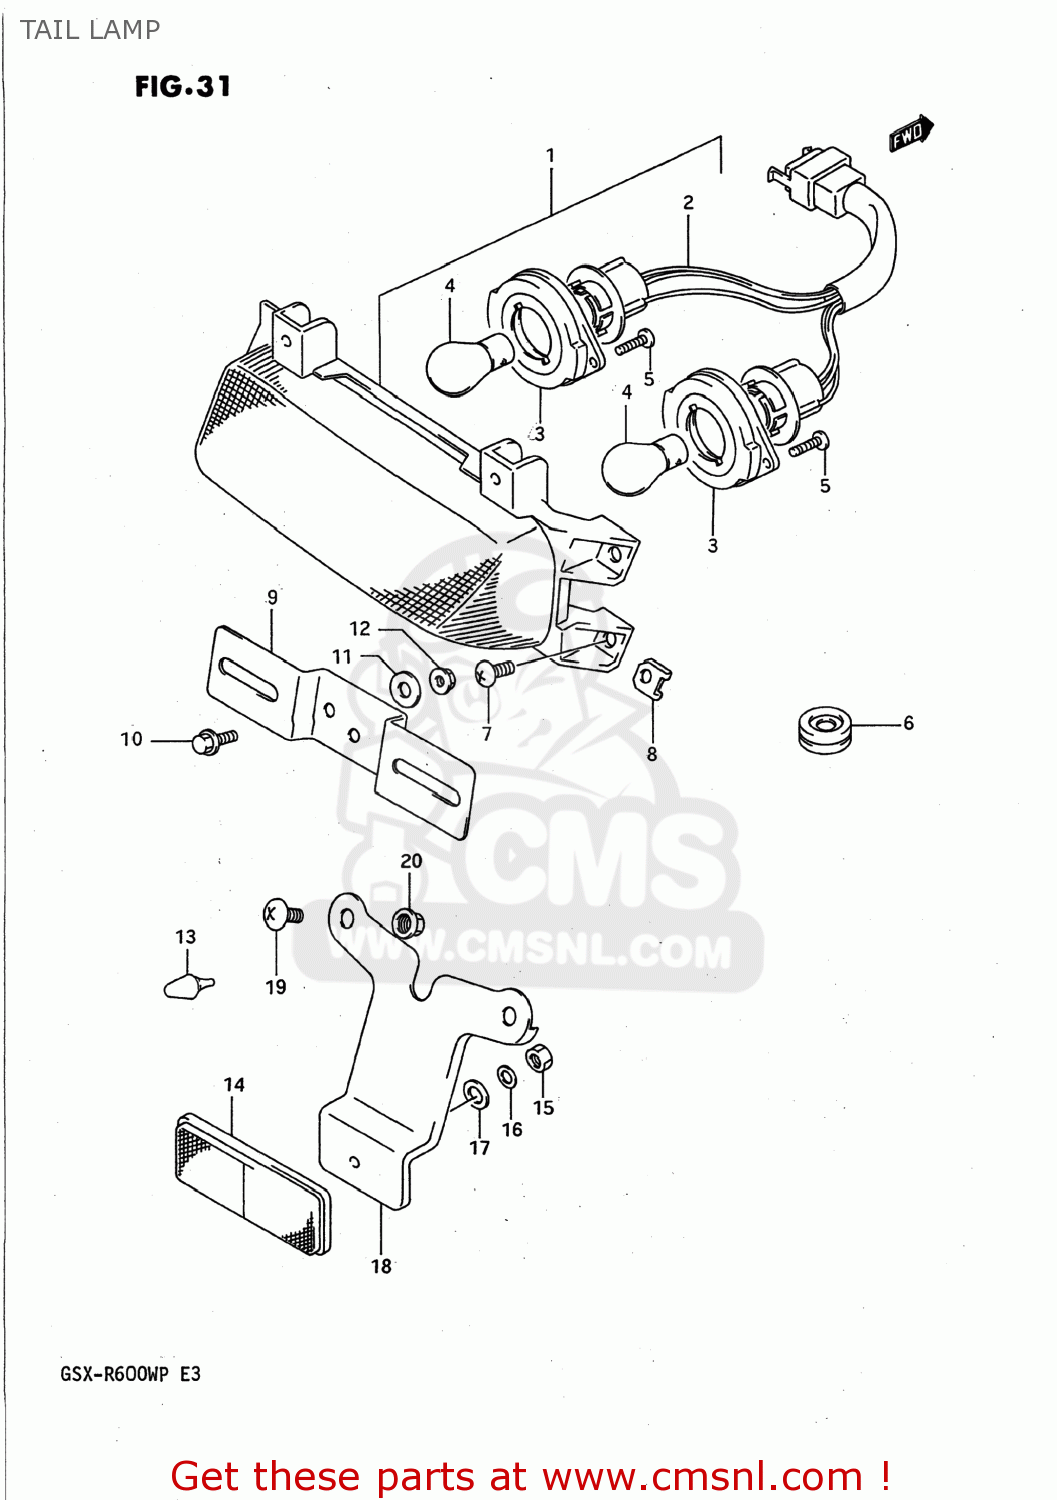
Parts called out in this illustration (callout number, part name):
1	LAMP ASSY,RR COMBINATION
2	SOCKET & CORD ASSY
3	CUSHION
4	BULB(12V21/5W,BF141-49642A)
5	SCREW
6	GROMMET
7	SCREW, FRONT & REAR
8	NUT
9	BRACKET,LICENSE PLATE
10	BOLT
11	WASHER,COVER,FRONT
12	NUT
13	CUSHION
14	REFLECTOR ASSEMBLY,REAR
15	NUT
16	WASHER,LOCK
17	WASHER,5MM
18	BRACKET,REAR,REAR
19	SCREW 6X12
20	NUT
